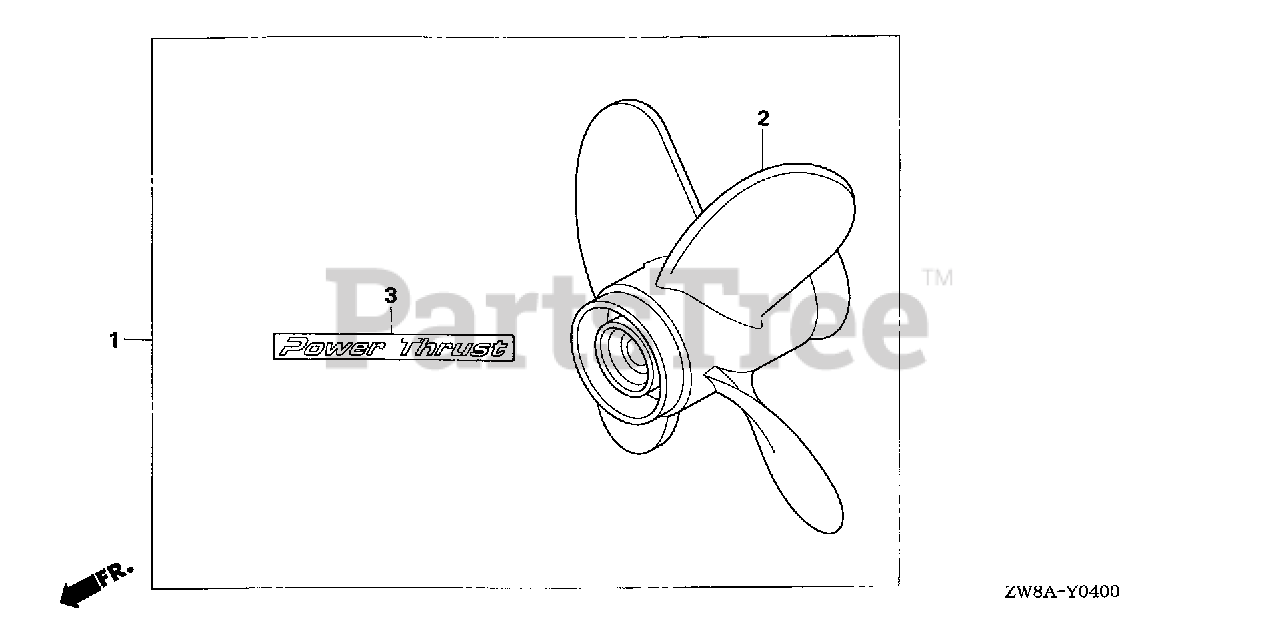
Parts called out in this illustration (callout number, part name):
1	PROPELLER KIT, POWER THRUST
1	PROPELLER KIT, POWER THRUST *NH283* (STIN GRAY)
2	PROPELLER, FOUR BLADES (10X6-1/2 HT) *NH283* (STIN GRAY)
3	MARK, POWER THRUST
